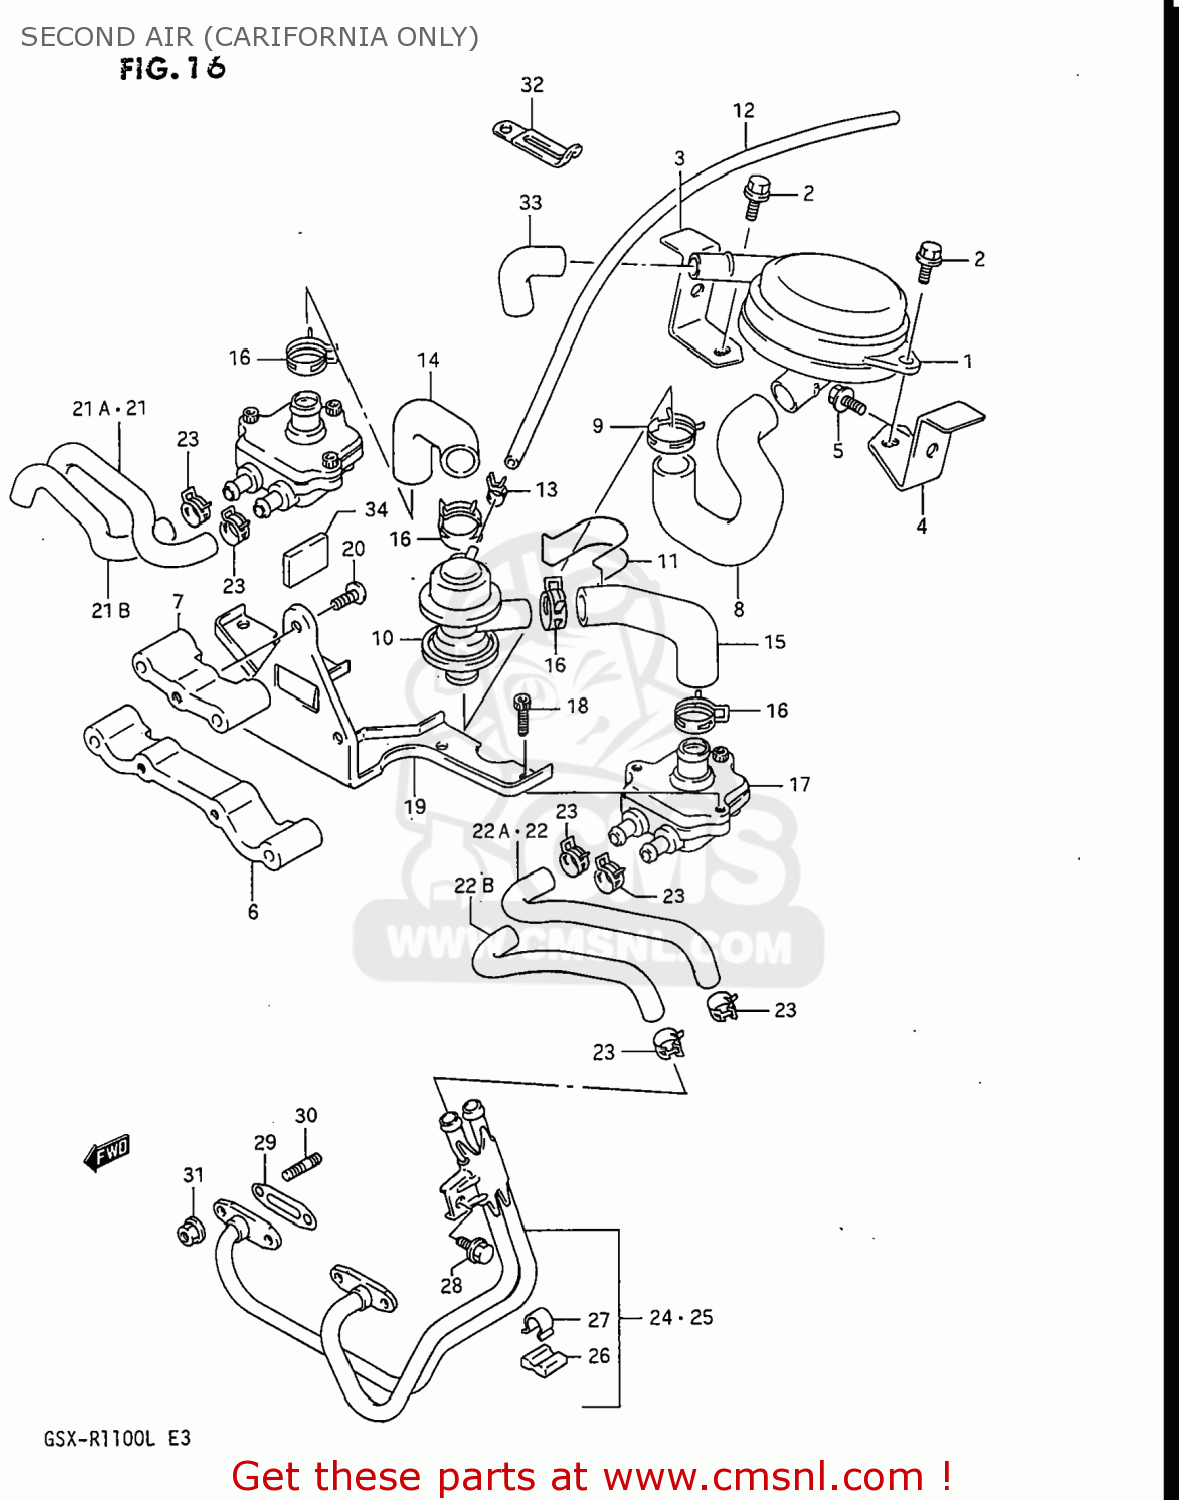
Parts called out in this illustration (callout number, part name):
1	CLEANER ASSEMBLY,SECOND AIR
2	BOLT
3	BRACKET,SECOND AIR CLEANER
4	BRACKET,SECOND AIR CLEANER
5	BOLT
6	SPACER,SECOND AIR BRACKET,LOWER
7	SPACER,SECOND AIR BRACKET,UPPER
8	HOSE,SECOND AIR NO.3
9	CLIP
10	VALVE ASSEMBLY,AIR SWITCH
11	CLAMP,SWITCHING VALVE
12	HOSE
13	CLAMP
14	HOSE,SECOND AIR NO.2,RIGHT
15	HOSE,SECOND AIR NO.2,LEFT
16	CLIP
17	VALVE ASSY,2ND AIR REED
18	BOLT
19	BRACKET,SECOND AIR VALVE
20	SCREW
21	HOSE,SECOND AIR NO.1,RIGHT
21A	HOSE,SECOND AIR NO.1,RIGHT,INLET
21B	HOSE,SECOND AIR NO.1,RIGHT,OUTLET
22	HOSE,SECOND AIR NO.1,LEFT
22A	HOSE,SECOND AIR NO.1,LEFT,INLET
22B	HOSE,SECOND AIR NO.1,LEFT,OUTLET
23	CLIP
24	PIPE ASSEMBLY,SECOND AIR,RIGHT
25	PIPE ASSEMBLY,SECOND AIR,LEFT
26	(CA) CUSHION
27	(CA) CLIP,SECOND AIR PIPE
28	BOLT 6X12
29	GASKET,SECOND AIR PIPE (NAS)
30	STUD BOLT
31	NUT 6MM
32	CLAMP L:35
33	(CA) HOSE,SECOND AIR CLEANER
34	CUSHION
